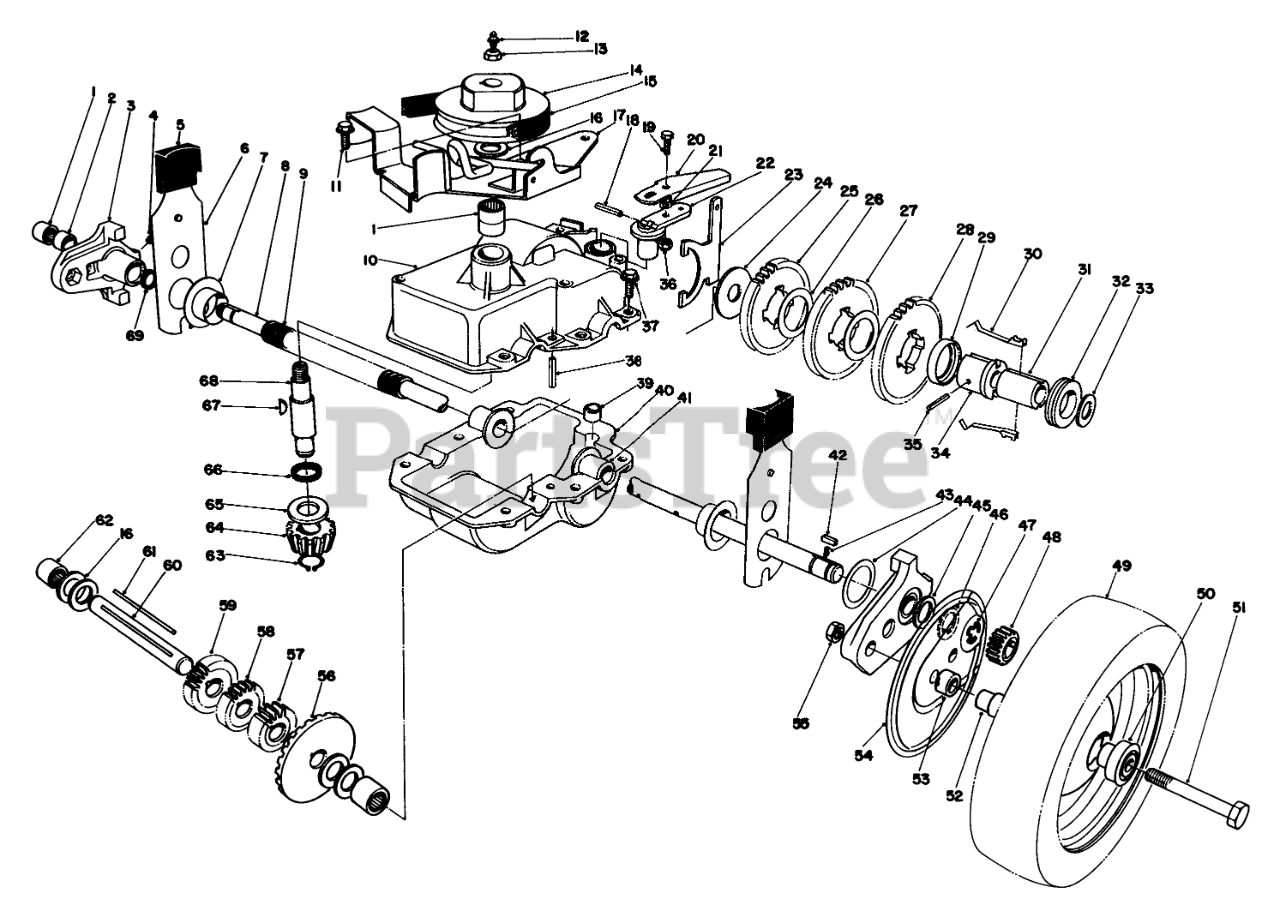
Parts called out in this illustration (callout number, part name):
1	BEARING-NEEDLE
2	BUSHING
3	Pivot Arm Assy. (Incl. Ref. #1-2, 4 & 69)
4	FITTING-GREASE
5	KNOB-ARM
6	Spring Arm
7	CAP-END
8	Output Shaft
9	CONDUIT-CONVOLUTED, SPLIT
10	Case Upper
11	SCREW
12	FITTING-GREASE
13	NUT-HEX
14	PULLEY
15	V-BELT
16	WASHER-THRUST
17	BELT GUIDE BRKT W A
18	PIN-COIL
20	Cover-Shift Lever
21	WASHER-FLAT
22	LEVER-SHIFT
23	Shift Yoke
24	WASHER
25	GEAR-38T
26	WASHER
27	GEAR-42T
29	KEY RETAINER
30	KEY-SHIFT
31	SLEEVE
32	COLLAR-SHIFT
33	WASHER-PLAIN
34	Body-Sleeve
35	PIN-ROLL
36	NUT-LOCK, NI
37	SCREW-HWHTF
38	ROLL PIN 3/16 X 1 IN
39	BUSHING-YOKE
40	Case-Lower
41	BUSHING
42	KEY RECTANGULAR
43	SPRING-COMPRESSION
44	WASHER
45	THRUST WASHER
46	KEYED WASHER
47	RING-RETAINING
48	GEAR-PINION
49	Wheel& Tire Assy. (Incl. Ref. #50 & 52)
50	BEARING-WHEEL
51	SCREW-HH
52	SPACER-BEARING
53	SPACER-WHEEL
54	WHEEL COVER
55	NUT-LOCK, NI
56	BEVEL GEAR
57	GEAR-12T
58	GEAR-14T
59	GEAR-18T
60	Shaft-Intermediate
61	Key Square
62	BEARING-NEEDLE, CLOSED
63	RING-RETAINING
64	PINION-BEVEL
65	WASHER-THRUST
67	KEY-WOODRUFF
68	Shaft Input
